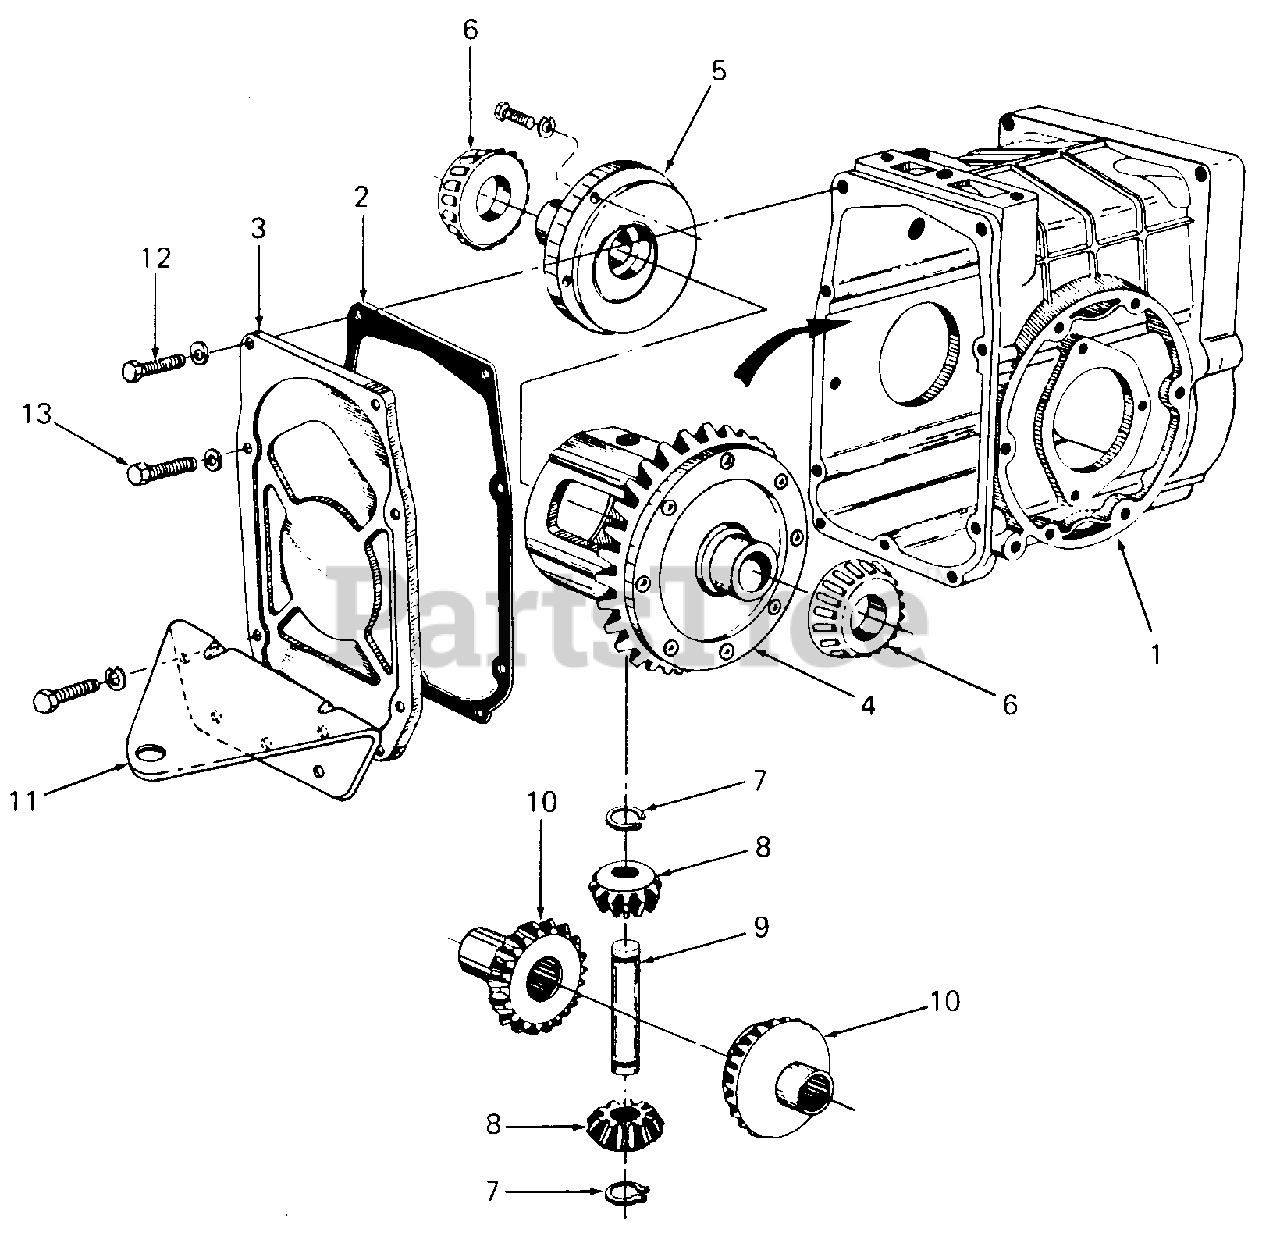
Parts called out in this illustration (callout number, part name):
1	Housing Assy, Rear Transaxle
2	Gasket, Rear Cover
3	Plate, Rear Cover
4	Gear Assy, Ring w/Case
5	Plate, Differential Flange
6	Cone, Roller Brg
7	Ring, Retaining, 11/16
8	Gear, Pinion - 10T
9	Shaft, Cross
10	Gear, Side - 16T
12	Bolt, Hex Patch, 3/8-16 x .62 Lg GR5
13	Bolt, Hex Patch, 3/8-16 x .75 Lg GR5
